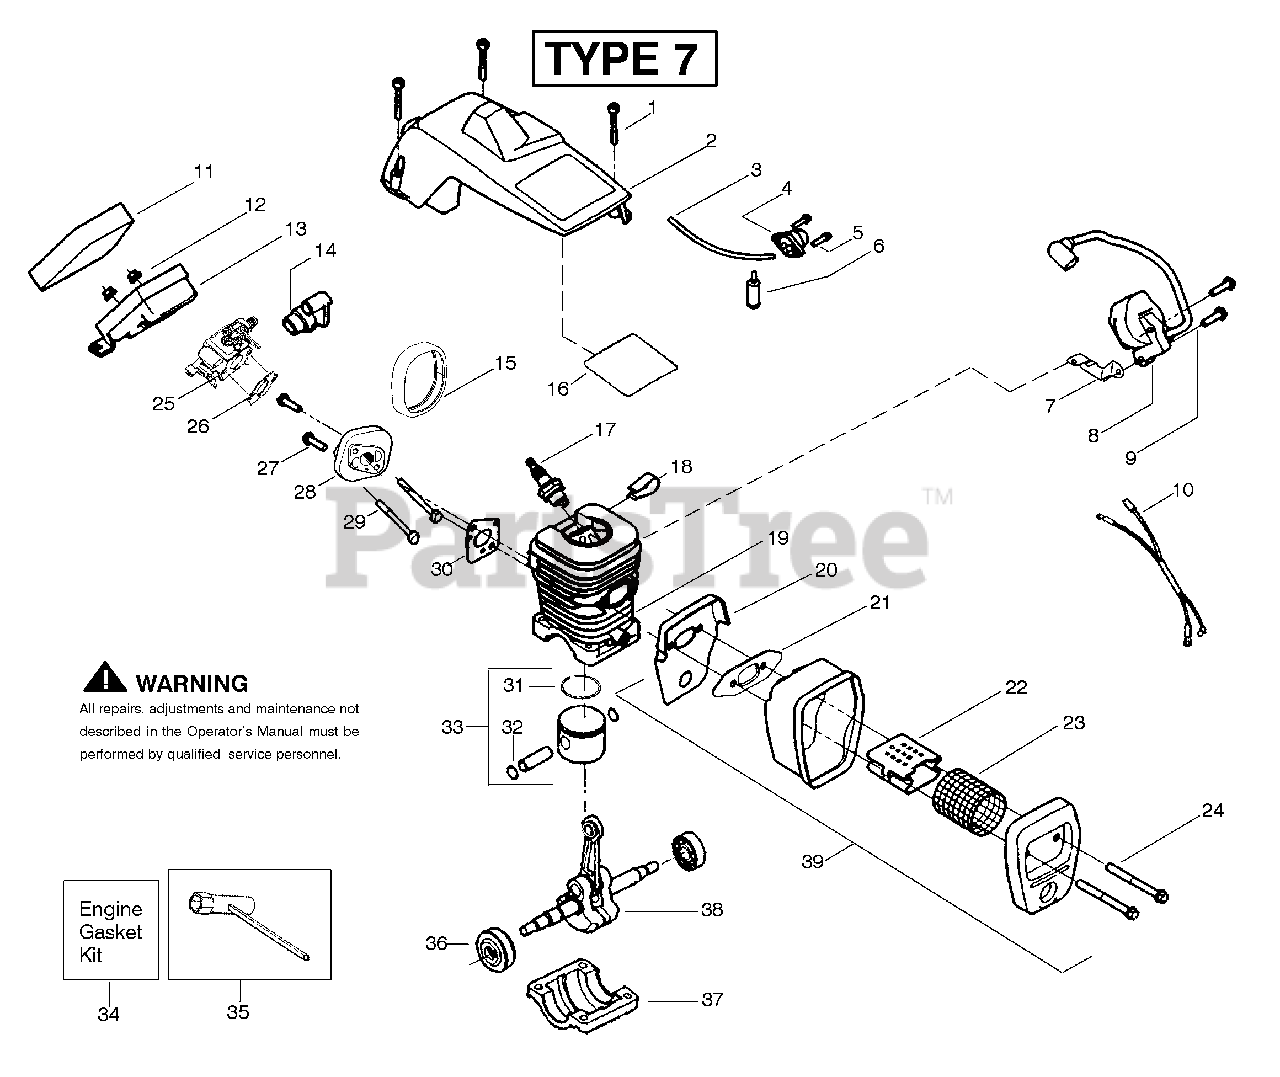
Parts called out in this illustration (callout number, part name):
2	Assy-Cylinder Shield
3	Kit-Fuel Line (Small)
4	Assy-Air Purge
6	Assy-Fuel Pick-up
7	Strap-Ground
8	Ignition Module
10	Assy-Wire Harness
11	Foam-Air Filter
13	Assy-Air Box
14	Grommet-Carb Adjust
15	Seal-Carb Adapter
16	Reflector-Heat
17	Spark Plug (RCJ-7Y)
18	Clip-High Tension Lead
19	Cylinder
20	Backplate-Muffler
21	Gasket-Muffler(kit)
22	Diffuser-Muffler
23	Screen-Spark
24	Bolt-Muffler
25	Kit-Carburetor Zama (W-20)
25	Kit-Carburetor Walbro (WT-662)
26	Gasket-Carb. (kit)
28	Carb. Adapter
30	Gasket- Adaptor(kit)
31	Ring-Piston
32	Retainer-Piston Pin
33	Kit-Piston
34	Kit-Engine Gasket
35	Bar Wrench
36	Assy-Seal & Bearing
37	Cap-Crankcase
38	Assy-Crankshaft
39	Assy-Muffler
